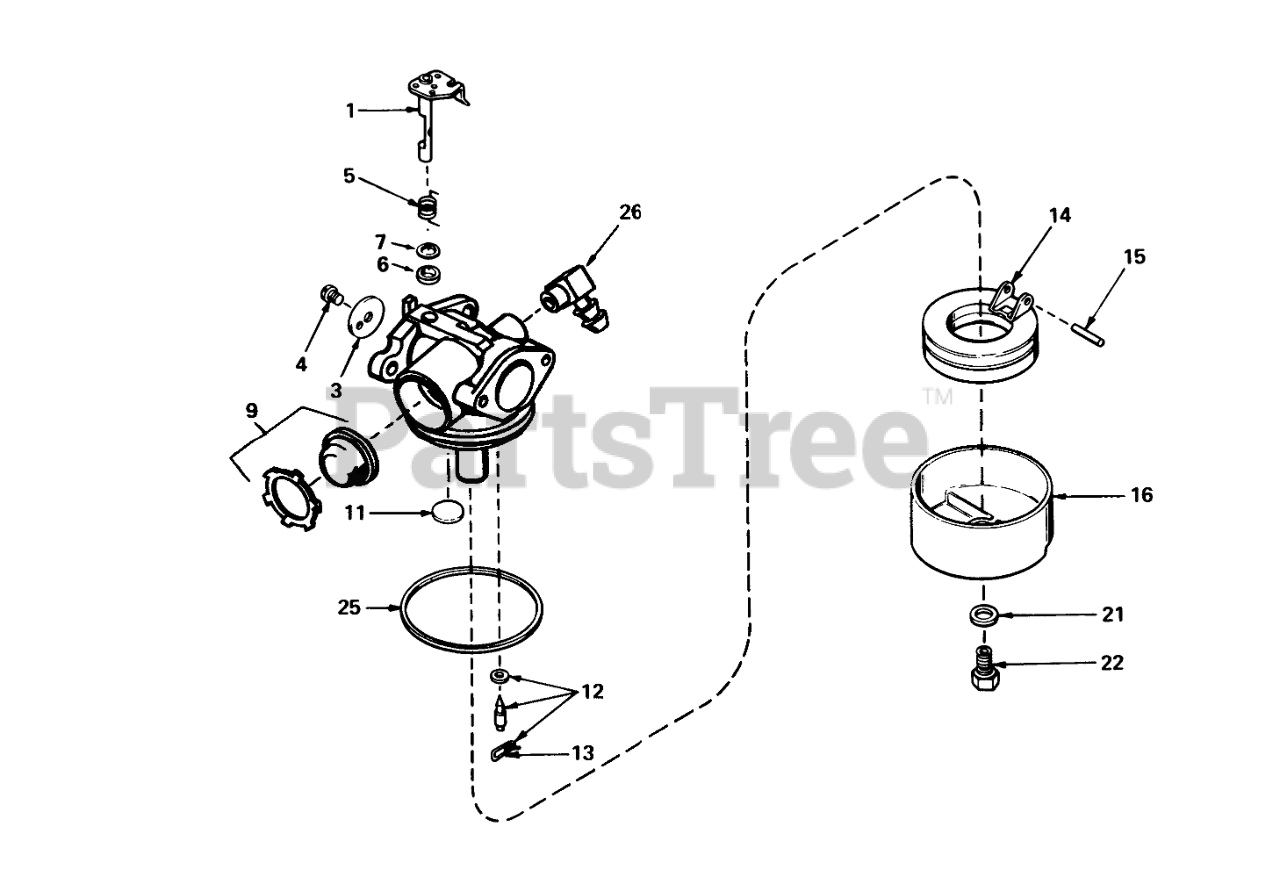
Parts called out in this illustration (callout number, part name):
1	Throttle Shaft and Lever ASM
3	Throttle-Shutter
4	Screw-Shutter
5	Spring-Return, Throttle
6	Seal-Dust
7	Washer-Seal, Dust
9	Primer Assy.
11	Plug-Welch, Atmospheric Vent
12	Inlet Needle-Seat & Clip Assy. (Incl. Ref. #13)
13	Clip-Spring
14	Float
15	Shaft-Float
16	Bowl Float
21	Gasket-Bowl
22	Nut-Float Bowl
25	O Ring-Bowl, Float
26	Fitting-Fuel
